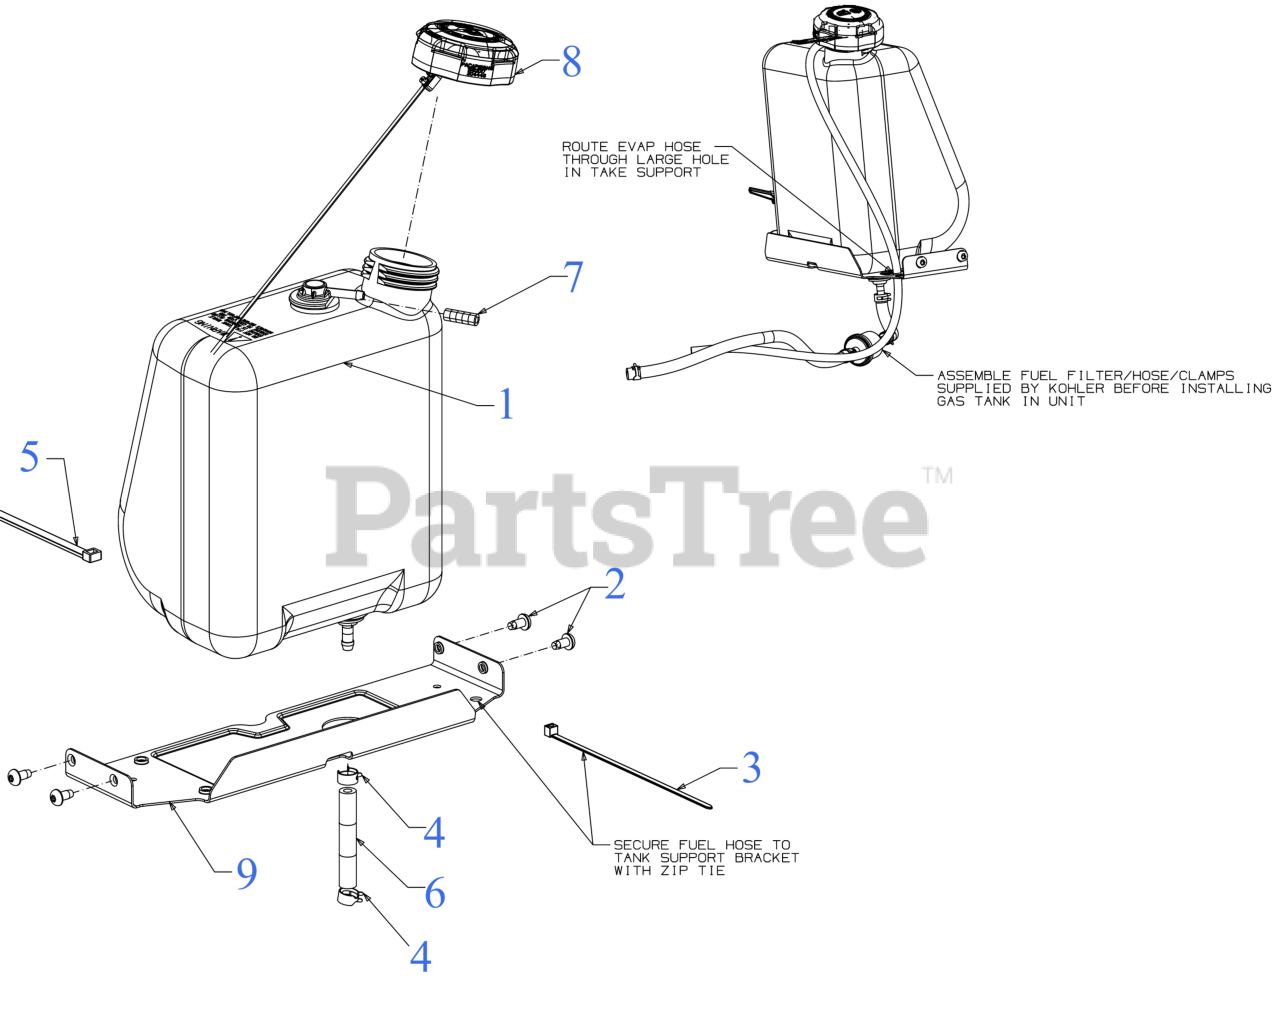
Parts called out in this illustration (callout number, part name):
1	FUEL TANK ASSEMBLY (1.36 Gal)
2	SCREW 1/4-20 x .5
3	7" CABLE TIE
4	HOSE CLAMP 1/20
5	CABLE TIE 36"
6	FUEL HOSE LOW PERMEATION 13"
7	VENT HOSE 3/16 ID 28"LG
8	FUEL CAP W/TETHER
